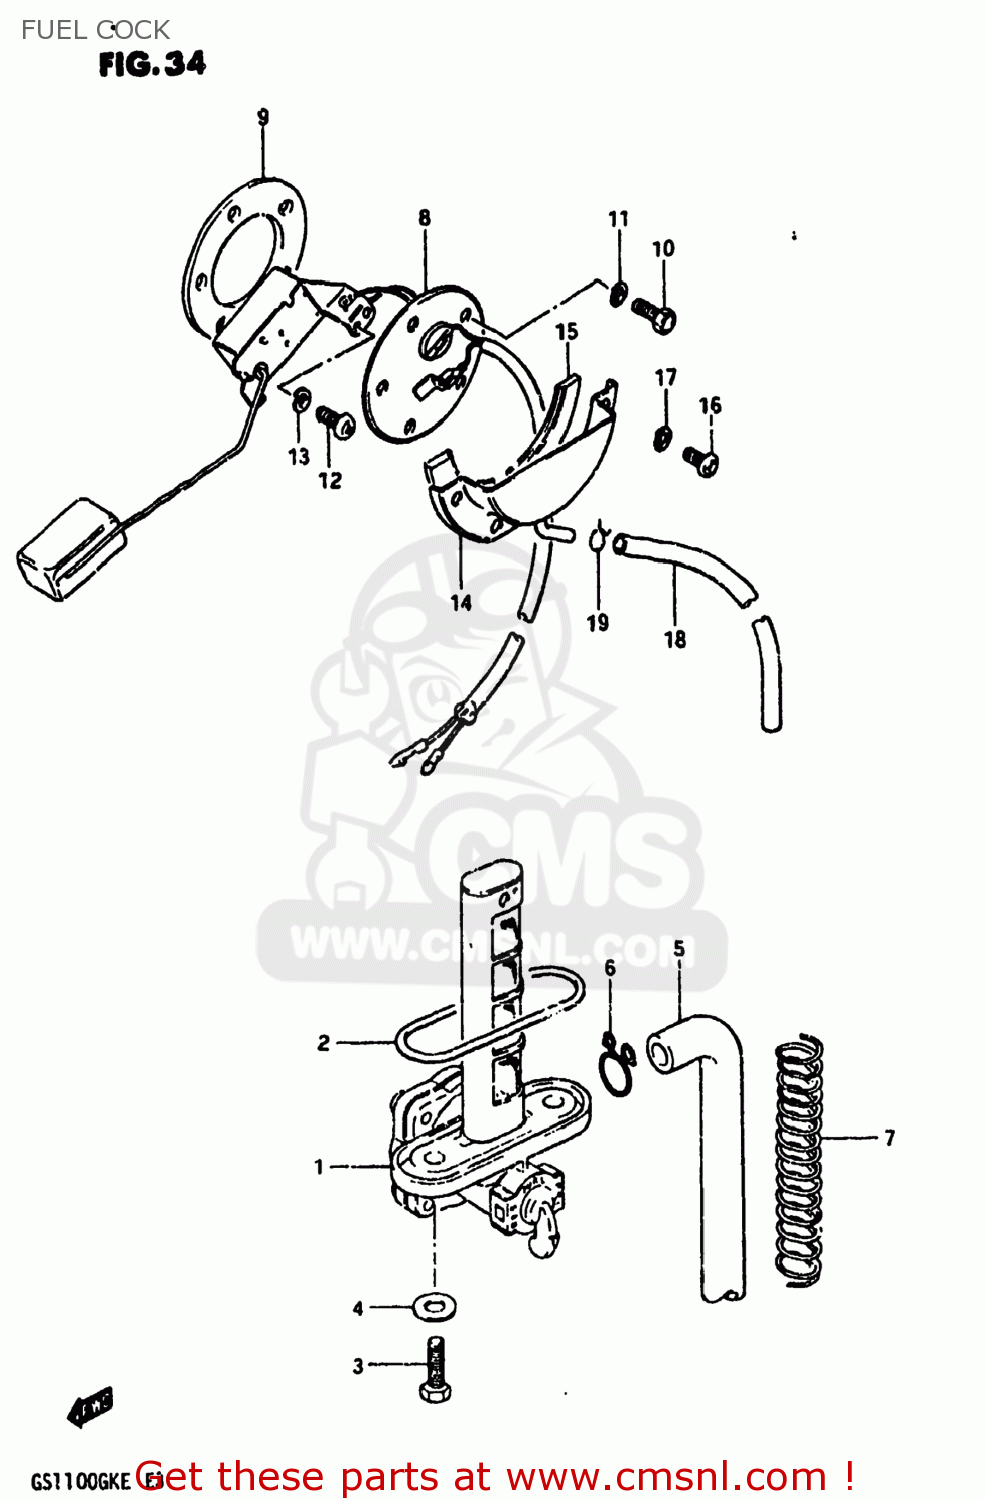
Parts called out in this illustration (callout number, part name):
1	COCK ASSEMBLY,FUEL
2	O RING
3	SCREW(6X20)
4	GASKET
5	HOSE
6	CLIP
7	SPRING
8	GAUGE ASSEMBLY,FUEL LEVEL
9	GASKET,FUEL LEVEL GAUGE (NAS)
10	BOLT 5X10
11	LOCK WASHER
12	SCREW
13	LOCK WASHER
14	PLATE,FUEL DRAIN
15	GASKET (NAS)
16	SCREW
17	LOCK WASHER
18	HOSE,FUEL
19	CLIP
